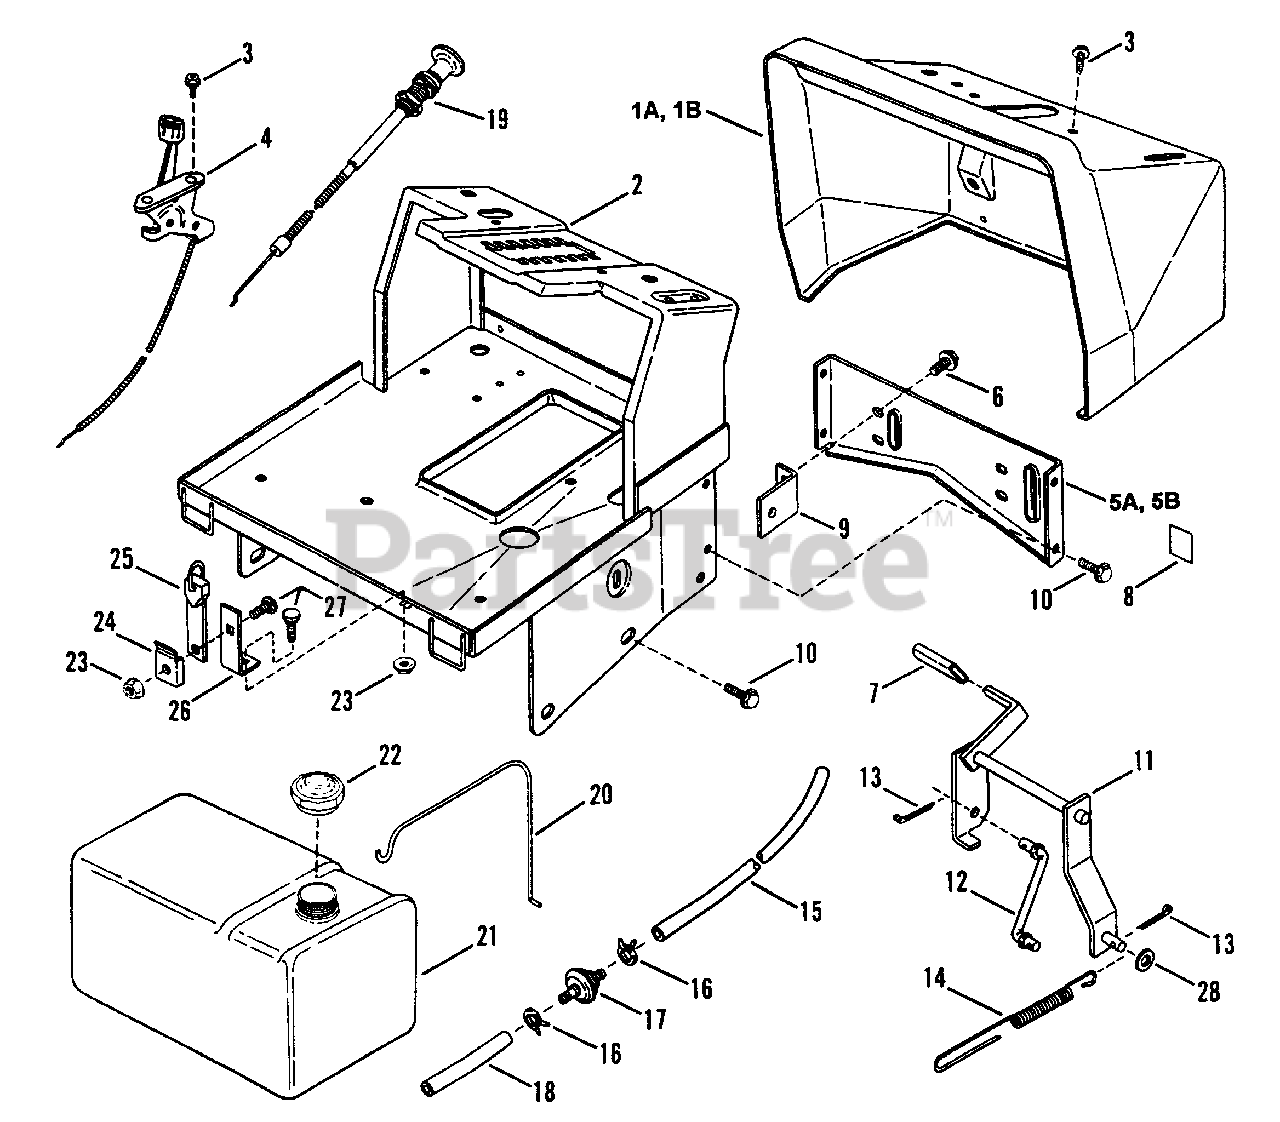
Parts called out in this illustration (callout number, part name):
1A	PANEL, Dash
1B	PANEL, Dash
2	PEDESTAL
3	SCREW, #10-24 x 1/2" Self-Tapping
4	CONTROL, Throttle
5A	BRACKET, Lower Dash
5B	BRACKET, Lower Dash
6	SCREW, 1/4-20 x 5/8" Self-Tap
7	SLEEVE, Parking Brake
8	DECAL, Cruise
9	BRACKET
10	SCREW, 5/16-18 x 5/8" Self-Tap
11	LEVER, Engagement
12	LATCH ROD
13	COTTER-PIN, 3/32 x 3/4"
14	SPRING
15	LINE, Fuel (12-1/2" Long)
16	CLAMP, Fuel Line
17	FILTER, Fuel (In-Line)
18	LINE, Fuel
19	CONTROL, Choke Cable
20	HOLD-DOWN, Fuel Tank
21	TANK, Fuel
22	CAP, Fuel Tank Filler
23	NUT, 1/4-20 Hex Flange Top Lock
24	CLIP, Hood Retainer
25	STRAP, Tank Hold-Down
26	BRACKET, Tank Hold-Down
27	BOLT, 1/4-20 x 5/8" Flat Head Carriage
28	WASHER, 3/8 SAE Flat
